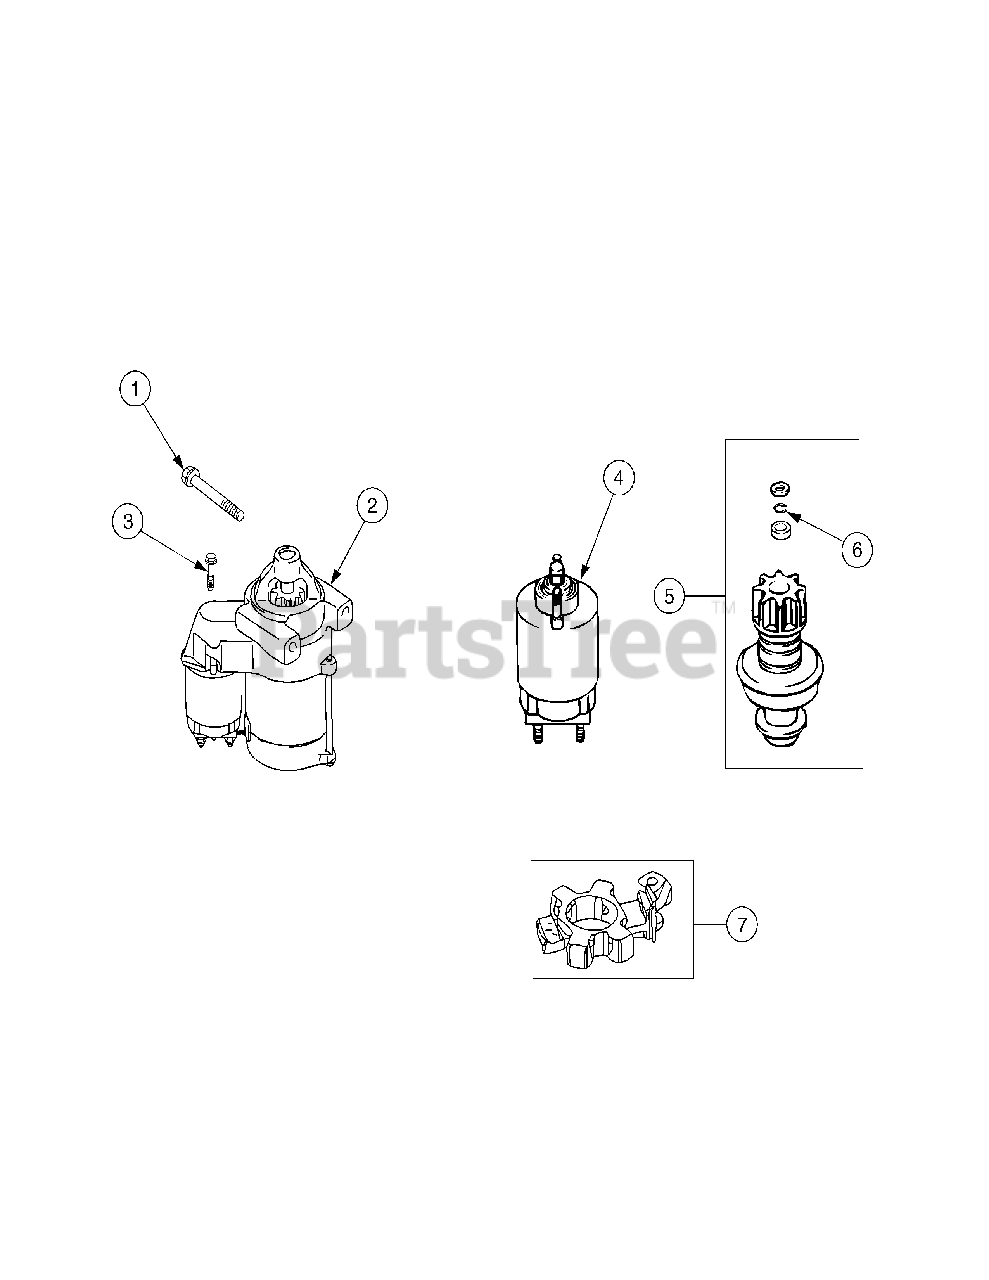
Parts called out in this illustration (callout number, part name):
1	Screw, Hx Flange, M8-1.25 x 80
2	Starter, Solenoid Shift
3	Screw, Torx Hd
4	Kit, Solenoid
5	Kit, Starter Pinion
